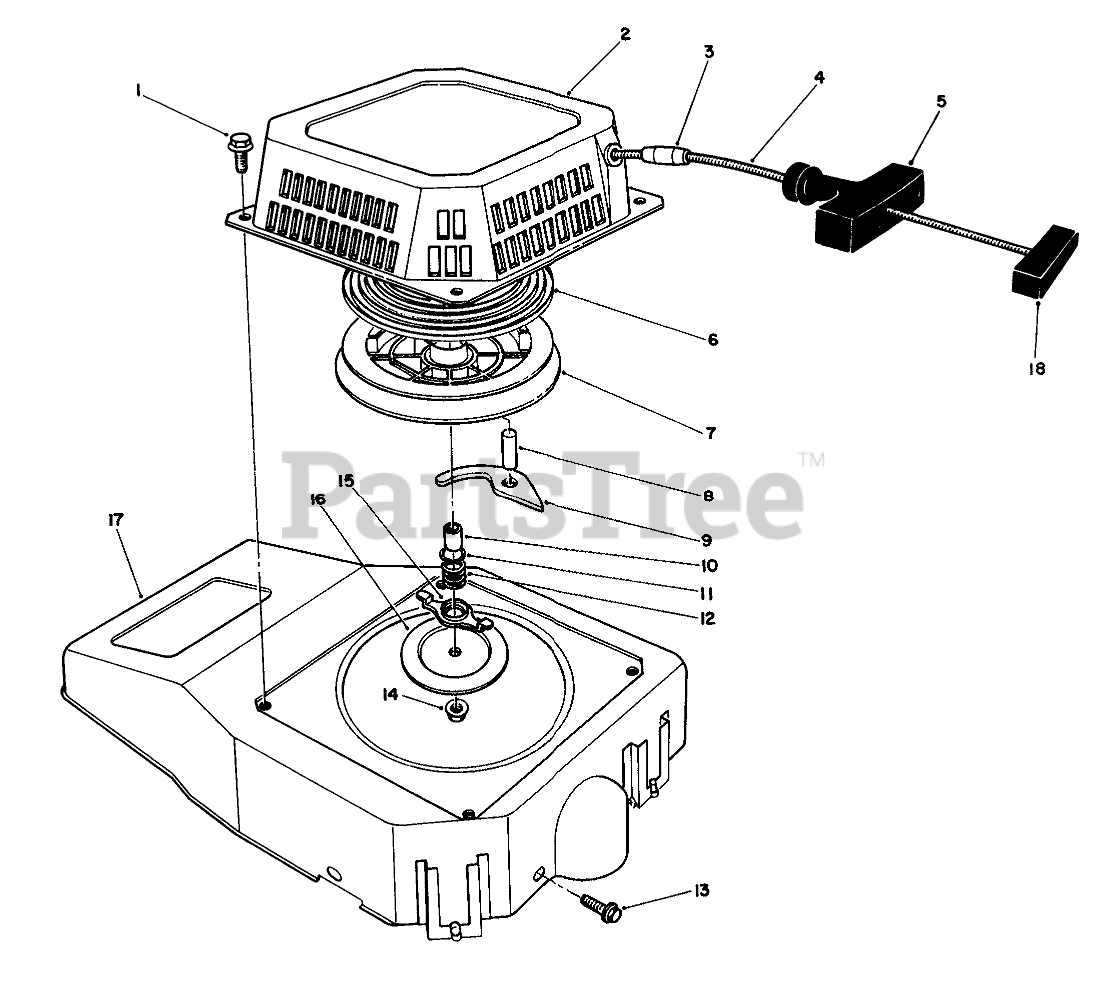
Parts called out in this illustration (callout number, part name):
1	SCREW-HHF
2	Case-Recoil
4	ROPE-STARTER
5	HANDLE
6	SPRING
10	Spacer
11	WASHER
12	Spring-Friction
15	Guide-Paw
16	PLATE
17	SHROUD
18	RETAINER HANDLE
